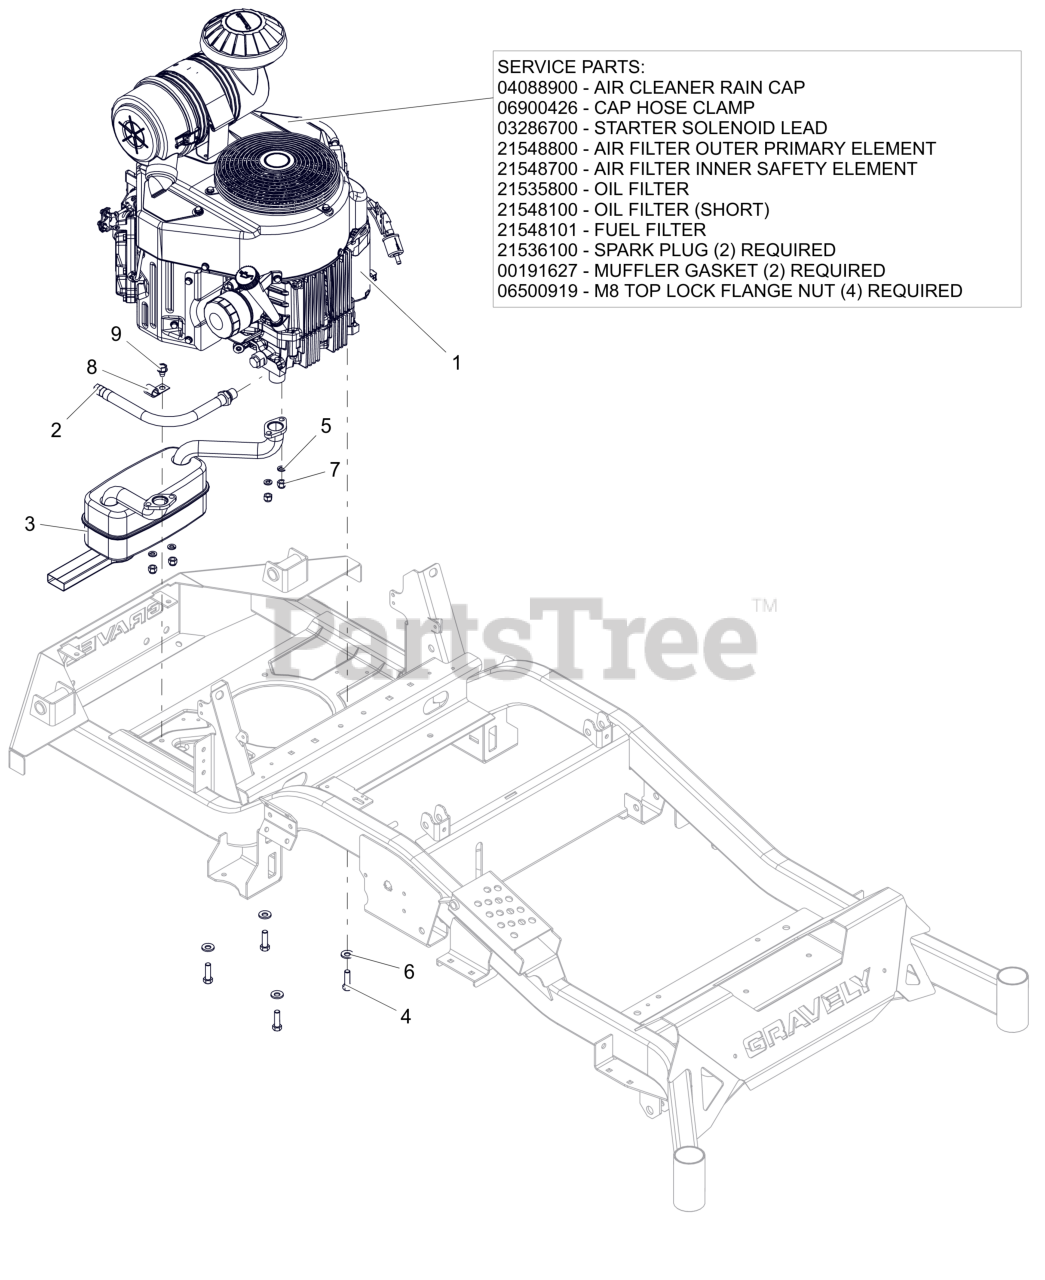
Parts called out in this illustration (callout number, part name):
1	ENGINE, KAWASAKI FX730
1	CAP, KAW 11065-7025
1	CLAMP, HOSE #36 SS 1.813-2.75
1	LEAD - STARTER SOLENOID
1	FILTER, OUTER
1	FILTER, INNER - KAW
1	FILTER,OIL - KAW
1	OIL FILTER, KAWASAKI FR
1	FUEL FILTER-KAWASAKI FR
1	PLUG, SPARK
1	GASKET, MUFFLER S/O
1	NUT-LK-TOP-FLG M8 ZCC
2	HOSE, OIL DRAIN
3	MUFFLER, KAWASAKI
4	BLT, HEX .38-16X1.25 G5 ZCC NT
5	WSHR,LK-REG .312X.078 ZCC
6	WASHER, 3/8" SPRING DISC
7	NUT,NYL M8-1.25 G8.8 ZCC
9	SCR,TAP .375-16X.50 HWH TR ZCC
